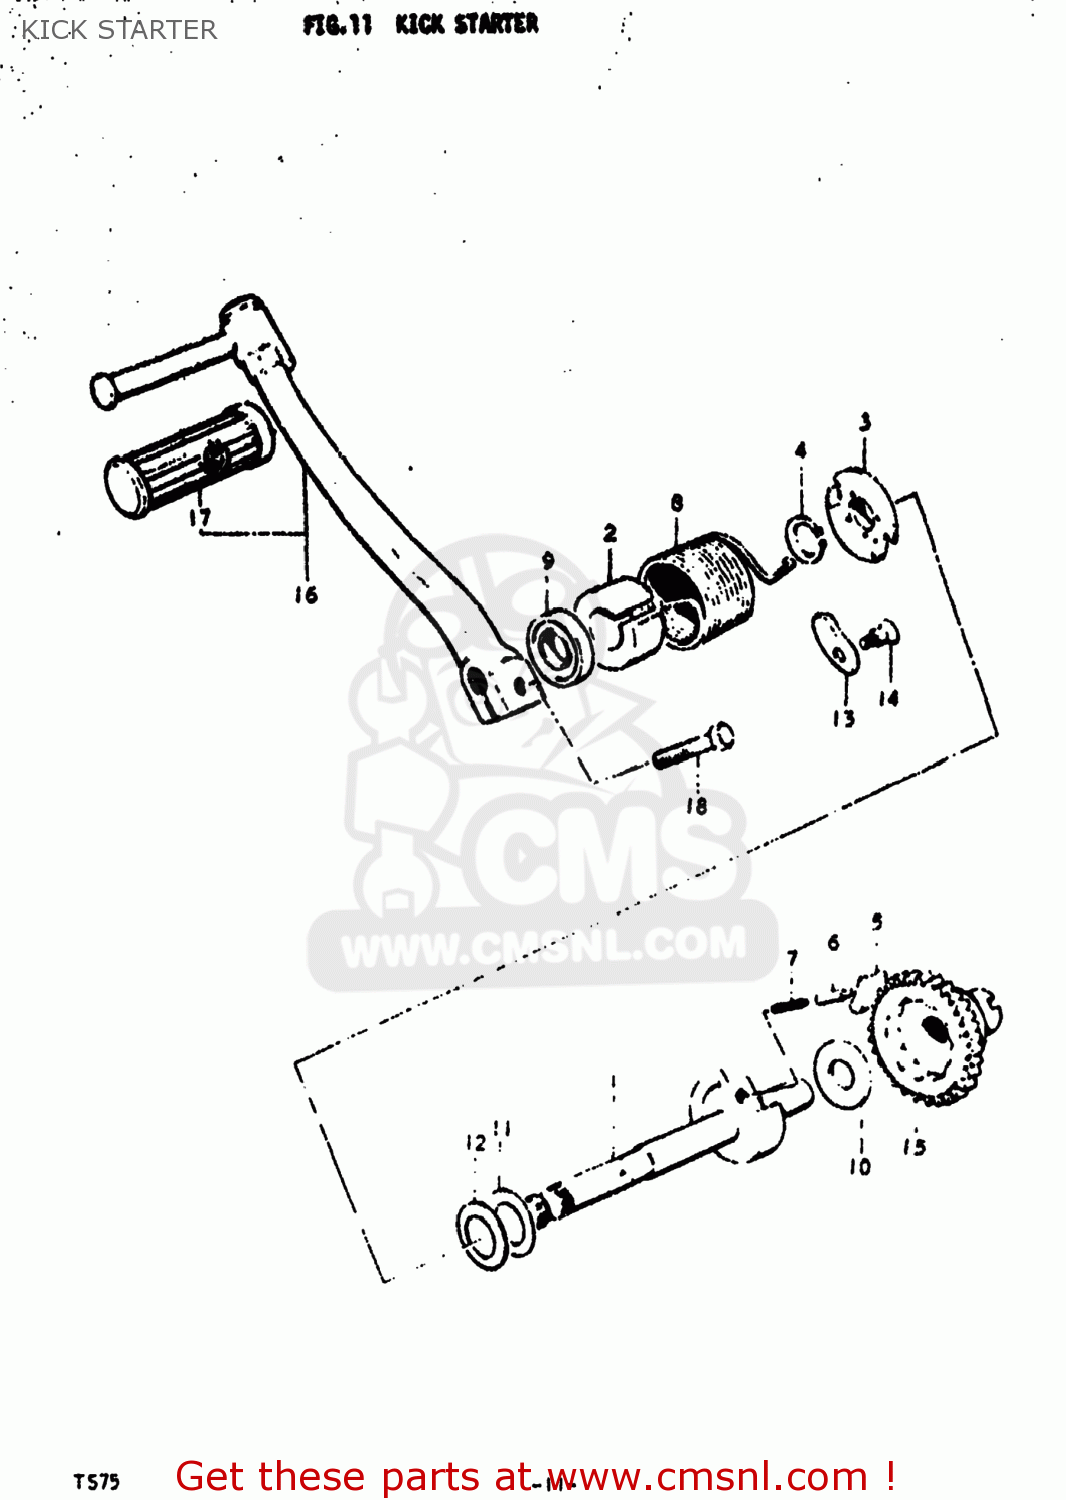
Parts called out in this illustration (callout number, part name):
1	SHAFT,KICK STARTER
2	GUIDE,KICK SHAFT SPRING
3	HOLDER,KICK STARTER SHAFT SPR
4	CIRCLIP
5	PAWL,KICK STARTER
6	PIN
7	SPRING
8	SPRING
9	SEAL,OIL(14X24X6)
10	WASHER
11	WASHER(14X29X0.8)
12	WASHER
13	LIFTER,KICK STARTER PAWL
14	SCREW(6X19)
15	GEAR,KICK STARTER DRIVE
16	LEVER ASSEMBLY,KICK STARTER
17	RUBBER,KICK STARTER PEDAL
18	BOLT
